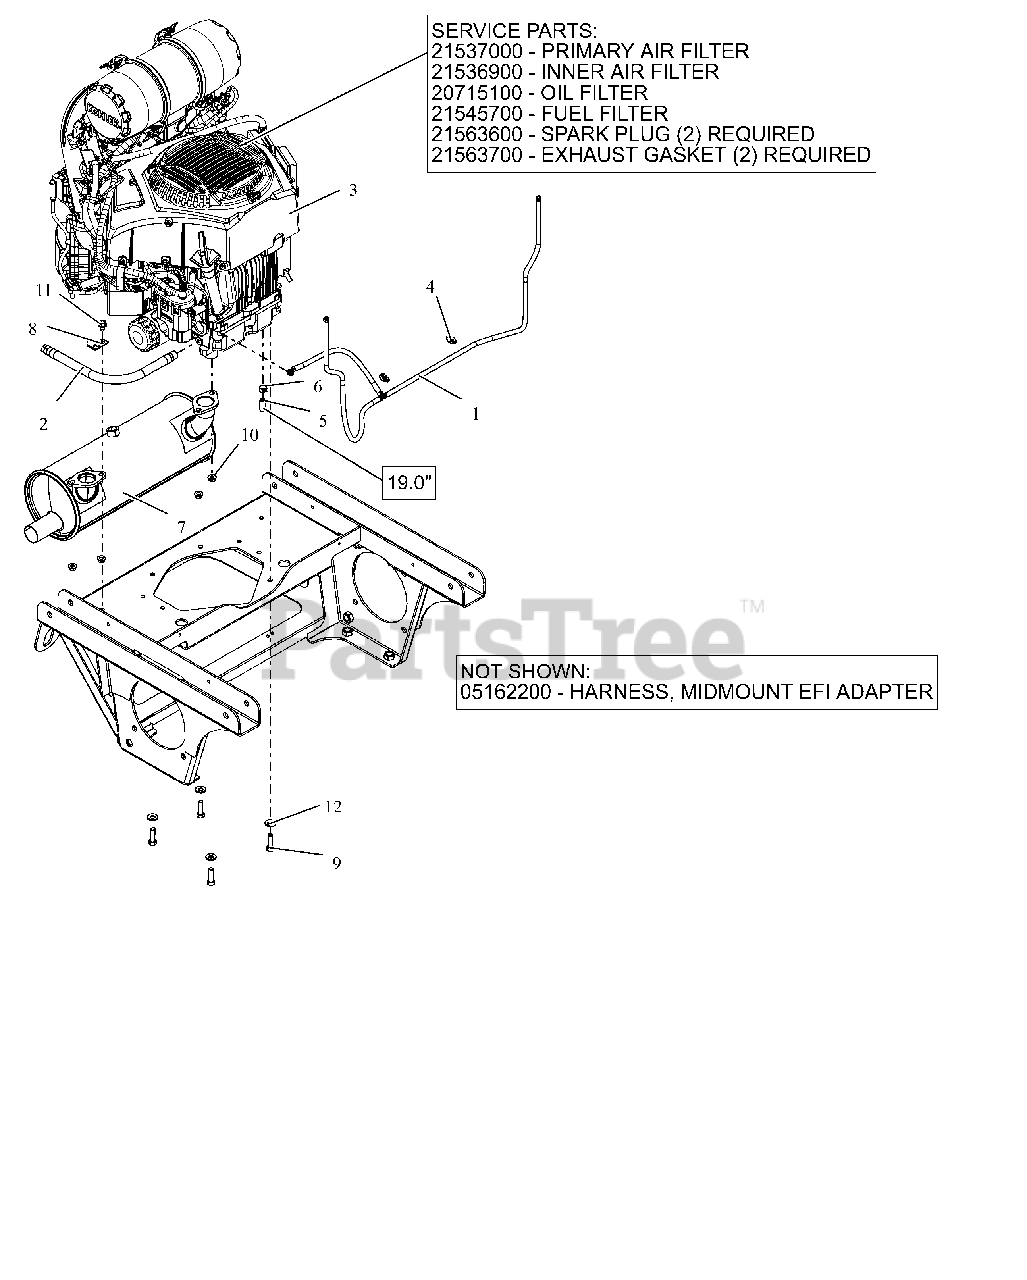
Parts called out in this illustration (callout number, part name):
1	ASM, KOHLER EFI VAPOR LINE
2	HOSE, OIL DRAIN
3	ENGINE, KOHLER EFI
3	ELEMENT, OUTER PRIMARY
3	ELEMENT, INNER SAFETY
3	OIL FILTER KOHLER
3	FILTER-FUEL KOHLER COURAGE PRO
3	PLUG, SPARK
3	GASKET, EXHAUST
4	ROUTING CLIP (1/2" ID)
5	HOSE, .25 LOW-PERM BULK GAS
6	CLAMP, FUEL LINE
7	MUFFLER, KOHLER EFI
9	BLT, HEX .38-16X1.25 G5 ZCC NT
10	NUT-LK-TOP-FLG M8 ZCC
11	SCR,TAP .375-16X.50 HWH TR ZCC
12	WASHER, 3/8" SPRING DISC
